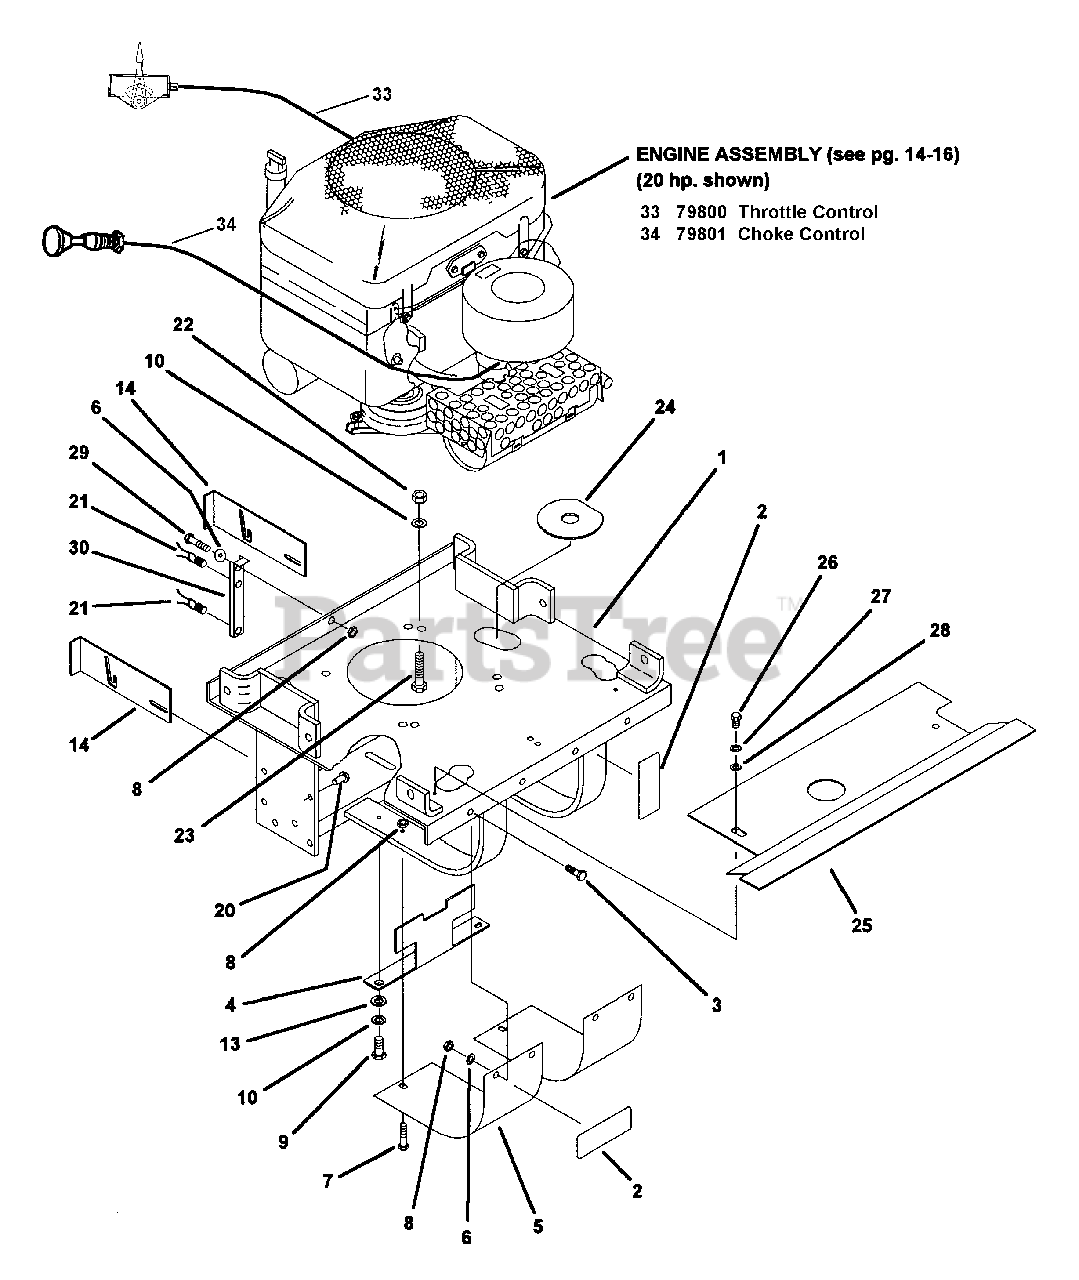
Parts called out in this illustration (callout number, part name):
1	MOTOR MOUNT WELDMENT
2	DECAL, FAN SHIELD
3	CAPSCREW, 1/4-20 X 3/4" GR. 5
4	CLUTCH STOP
5	FAN SHIELD
6	WASHER, FLAT, STD. 1 /4"
7	CAPSCREW, 1/4-20 X 1" GR. 5
8	NUT, HEX HD. 1/4-20, NYLOC
9	CAPSCREW, HEX. 5/16-18 X 3/4" GR. 5
10	LOCKWASHER, 5/16" SPLIT SPRING
13	WASHER, FLAT STD. 5/16"
14	FREEWHEEL BAR
20	DRIVE STUD, 1/4 X 1/2" LONG
21	BLINDHOLE KURLY-LOC
22	NUT, 5/16-24 UNF, GR. 5 PLATED
23	BOLT, 5/16-24 X 1-1/2" GR. 5
23	BOLT, M8 X 1.25 X 25 HEX HD.
24	WASHER, SEAL
25	REAR SHIELD
26	SCREW, 1/4 X 3/8" SELF THRD. FORM
27	LOCKWASHER, SPLT. SPRING 1/4"
28	WASHER, FLAT 1/4" ZINC PLATED
29	CAPSCREW, 1/4-20 X 5/8" GR.5
30	BRACKET, CLUTCH WIRE
33	Throttle Control
34	Choke Control
